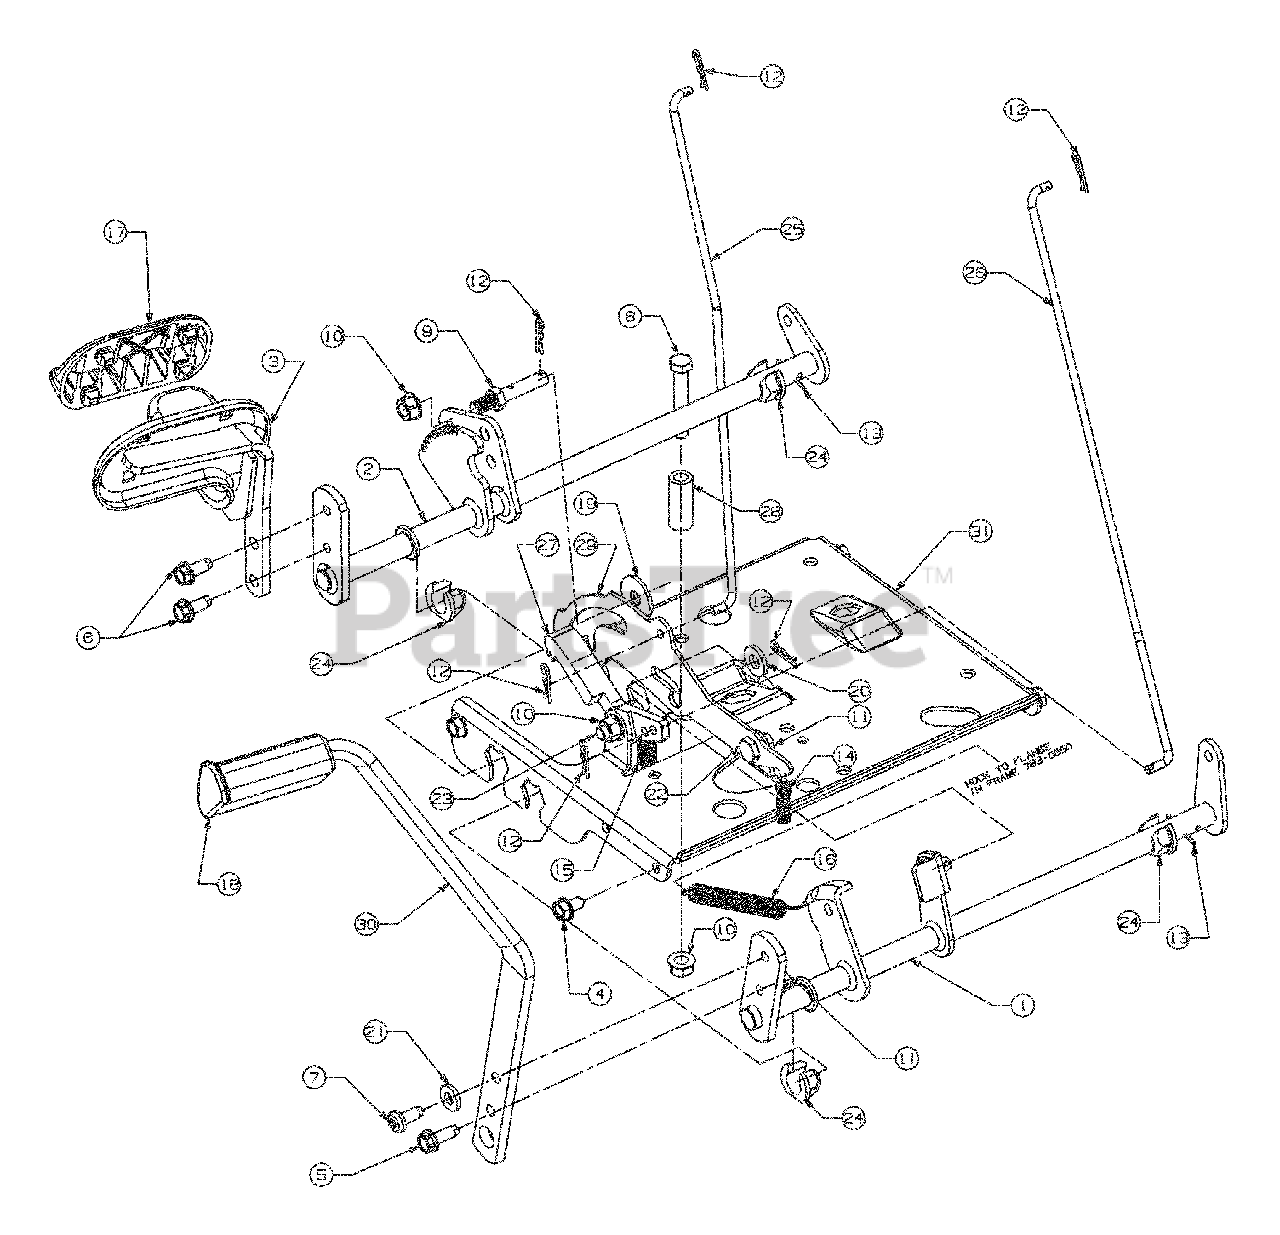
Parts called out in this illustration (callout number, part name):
1	CONT ASM:BRAKE:500
2	CONT ASM:HYDRO:500 LONG
3	PED ASM:CONT:HYDRO
4	SCR:TT:5/16-18:0.625:HXINDWSH
5	SCR:TT:5/16-18:0.875:HXINDWSH
6	SCR:LD:5/16-18:0.750:HXINDWSH
7	SCR:TT:5/16-18:0.750:PANTRXI
8	HHCS:3/8-16:2.25:GR5:STD
9	PIN:3/8-16:3/8 X 2.43 LG
10	NUT:FLGLK:3/8-16:GRF:TOP LK
11	NUT:FLGLK:5/16-18:GR5:SD LK
12	PIN:COT:.072 DIA. X 1.13 LG
13	PIN:COT:3/32:1.0
14	SPR:COMPRS:.405 X 1.17
15	SPR:EXTN:.50 OD X 1.41 LG
16	SPR:EXTN:.50 DIA X 6.37 LG
18	PAD:BRAKE:CONTROL
19	WASH:FLAT:.411 X 1.25 X 1.00
20	WASH:FL:.406IDX.875ODX.105
21	WASH:FL:.344 X .750 X .120
22	SHLD SCR .437 DIA X .162
23	SCR:SHLDER:.500 DIA X .434
24	BRG:HEX FLG:.628 ID:SPLIT
25	ROD:CONT:BRAKE LOCK
26	ROD:CONT:CRUISE:8&9 STL
28	SPCR:.385 ID X .635 OD X 1.54
31	BRKT:SUPT:STRG:500
